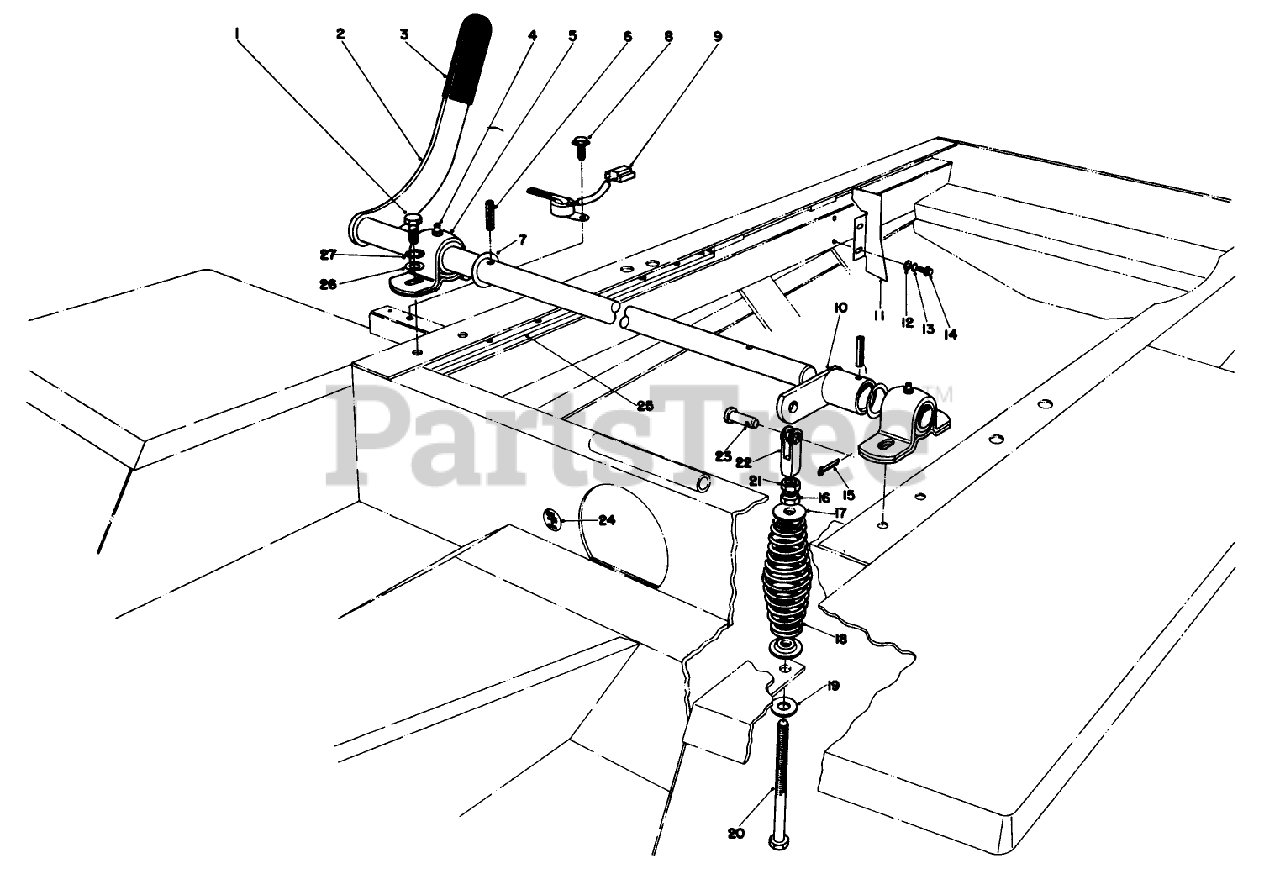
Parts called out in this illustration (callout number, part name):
1	SCREW-HH
3	GRIP-HANDLE
4	FITTING-GREASE
5	BEARING
6	PIN-SPRING
7	THRUST WASHER
8	SCREW-HWHTF
12	WASHER-PLAIN
13	SCREW-HH
14	SCREW-THD ROLL, HWH
15	SCREW-HH
16	NUT-HEX
17	SPRING RET TOP
19	WASHER
20	SCREW-ADJUSTING
21	NUT-HJ
23	PIN-CLEVIS
24	OIL DECAL
26	WASHER-FLAT
27	SCREW-HH
